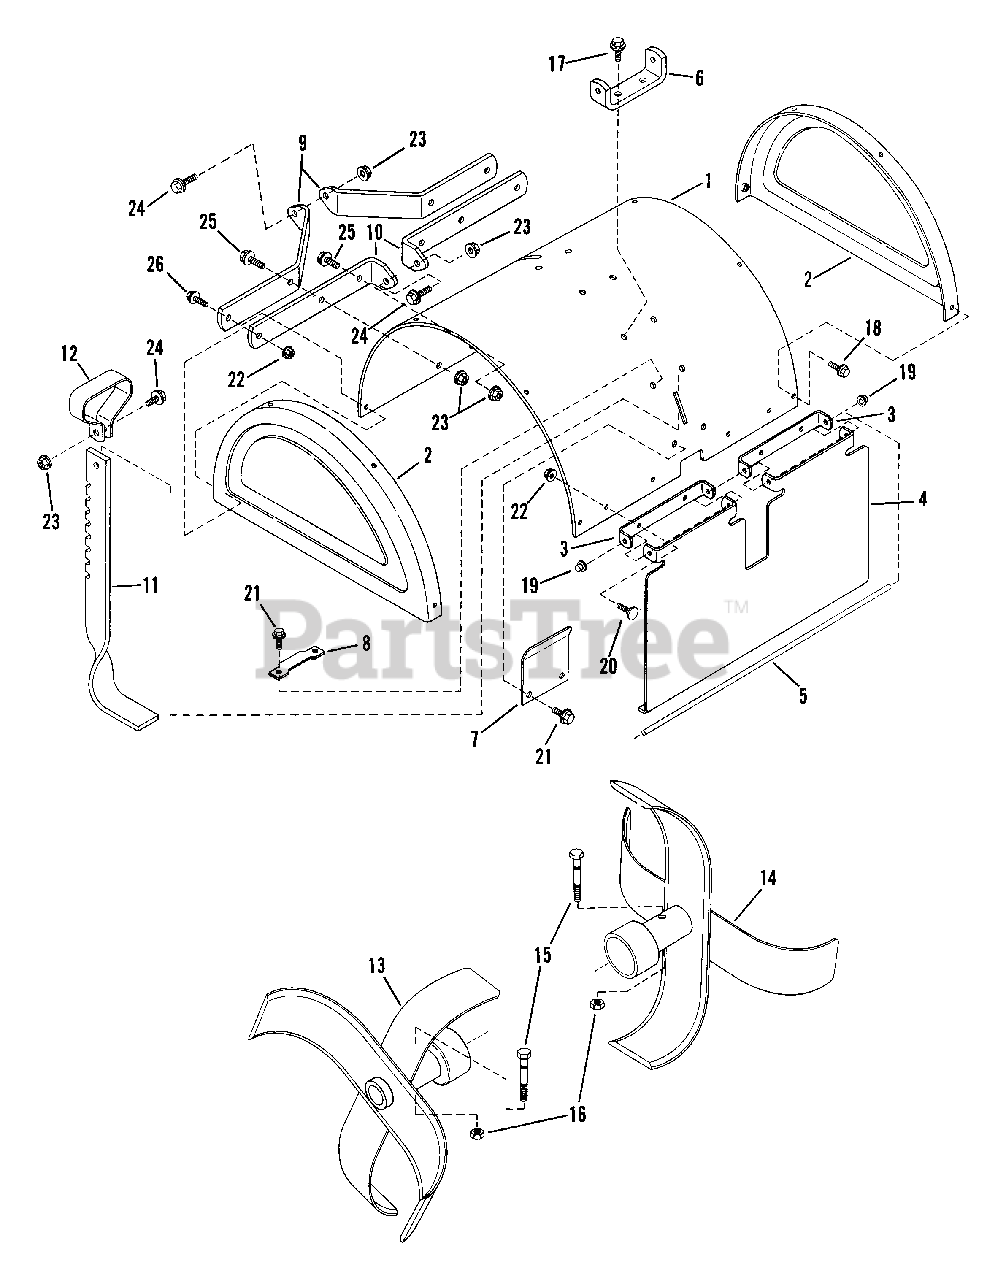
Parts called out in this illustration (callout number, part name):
1	COVER, Tine
2	COVER, Side Tine
3	HINGE, Half
4	SHIELD, Drag
5	PIN, Drag Shield
6	BRACKET, Support
7	SPRING, Depth Bar
8	PLATE, Latch
9	REINFORCEMENT, Front Tine Cover
10	REINFORCEMENT, Rear Tine Cover
11	BAR, Depth
12	HANDLE, Depth Bar
13	STRUCTURE, Left Tine
14	STRUCTURE, Right Tine
15	BOLT, 5/16-24 x 2" Shear
16	NUT, 5/16-24 Hex Lock
17	SCREW, 5/16-18 x 3/4" Self-Tapping
18	SCREW, 1/4-20 x 3/8" Self-Tapping
19	NUT, 1/4 Push
20	BOLT, 1/4-20 x 1/2" Flat Head Carriage
21	SCREW, 5/16-18 x 5/8" Self-Tapping
22	NUT, 1/4-20 Hex Flange Lock
23	NUT, 5/16-1B Hex Flange Lock
24	BOLT, 5/16-18 x 1" Hex Flange Lock
25	BOLT, 5/16-18 x 5/8" Hex Flange Lock
26	SCREW, 1/4-20 x 3/4" Self-Tapping
